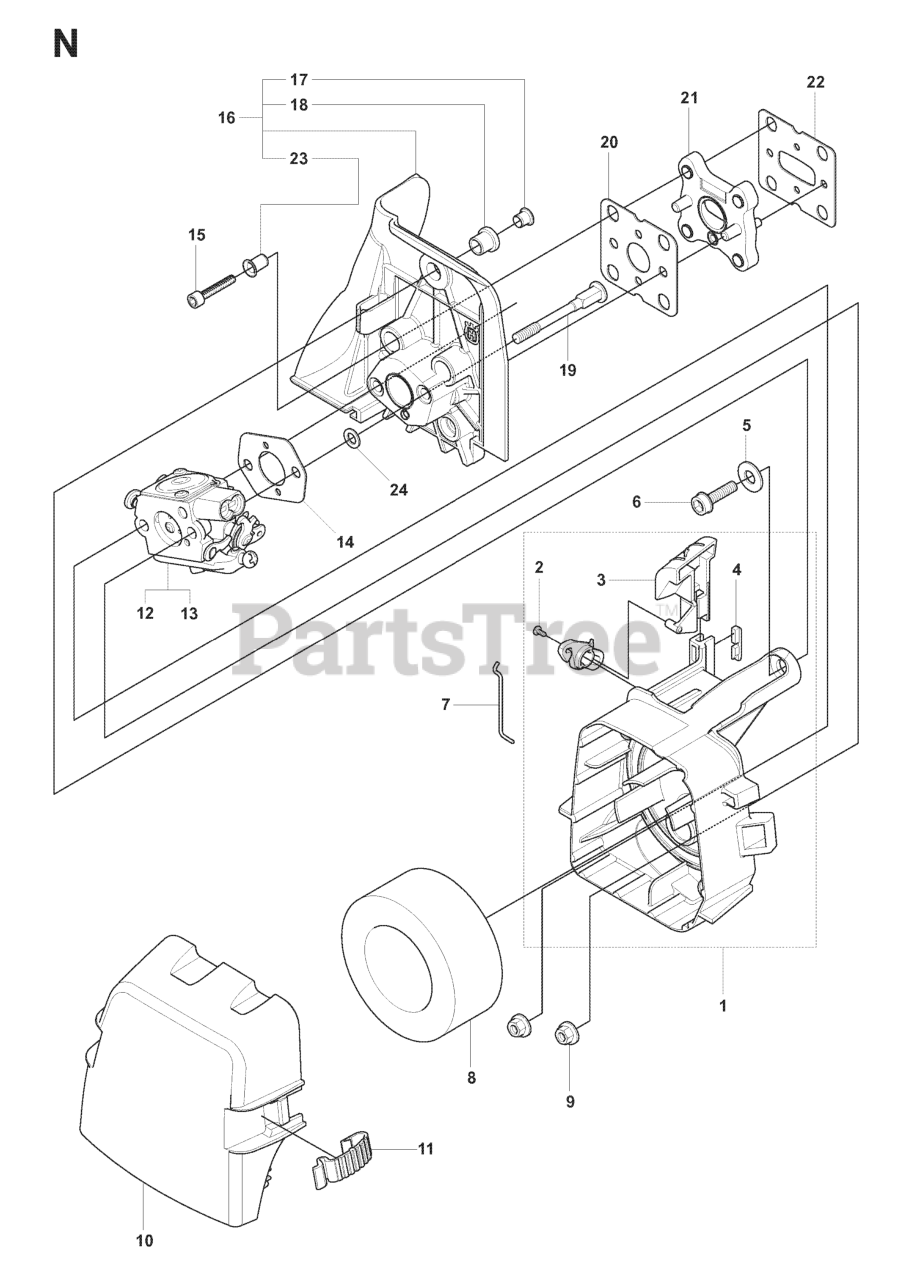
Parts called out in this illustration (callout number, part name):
1	FILTER HOLDER ASSY
3	CHOKE CONTROL
6	SCREW IHSCFM
10	FILTER COVER
12	CARBURETTOR C1Q-EL38
13	CARBURETTOR C1Q-EL39A
15	SCREW
16	INSULATION WALL ASSEMBLY
20	GASKET INTAKE
22	GASKET INTAKE
24	WASHER
